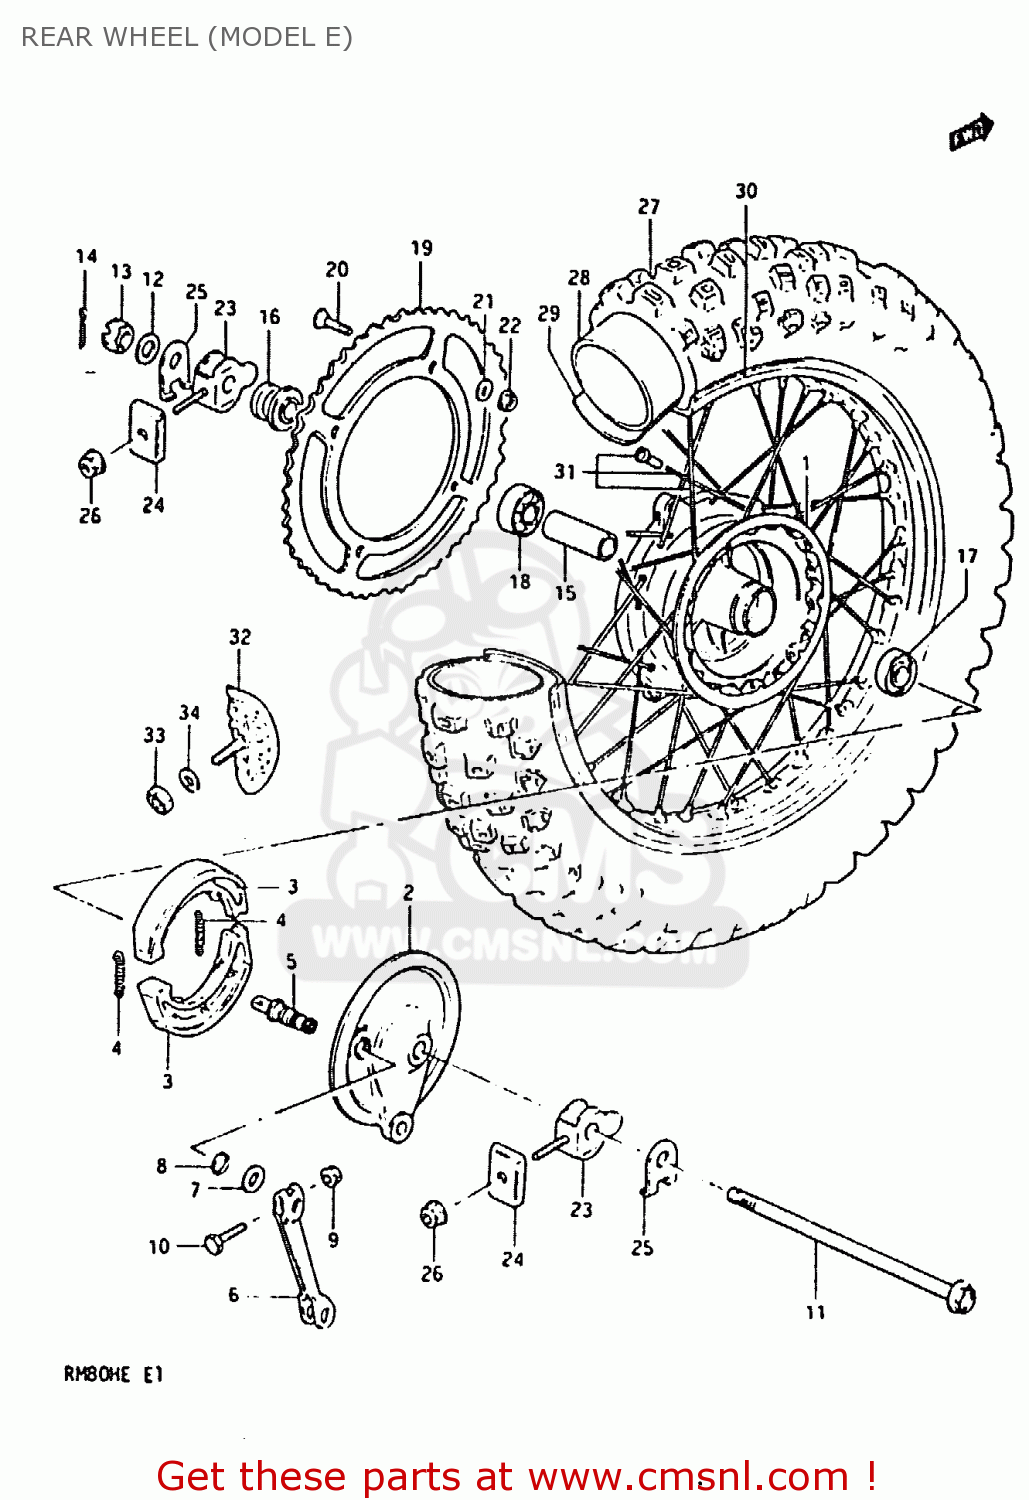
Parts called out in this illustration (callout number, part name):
1	DRUM, REAR HUB
2	PANEL, REAR HUB
3	SHOE,BRAKE
4	SPRING, BRAKE SHOE
5	CAM,FRONT BRAKE
6	LEVER,RR BRAKE CAM
7	WASHER(12.5X20X1)
8	O RING(D:2.5,ID:11.4)
9	NUT
10	BOLT
11	AXLE,REAR
12	WASHER
13	NUT
14	COTTER PIN
15	SPACER(15.3X21.7X77)
16	SPACER,L
17	BEARING
18	BEARING
19	SPROCKET, REAR
20	SCREW(8X33.5)
21	WASHER
22	NUT
23	ADJUSTER,CHAIN
24	ADJUSTER,CHAIN
25	WASHER,CHAIN ADJUSTER
26	NUT
27	TIRE, REAR (3.50*18)
28	TUBE ASSEMBLY,WHEEL,INNER
29	PROTECTOR,INNER TUBE
30	RIM, WHEEL (1.85*18 AL)
31	SPOKE ASSY,RR WHEEL
32	STOPPER,BEAD
33	NUT
34	WASHER
